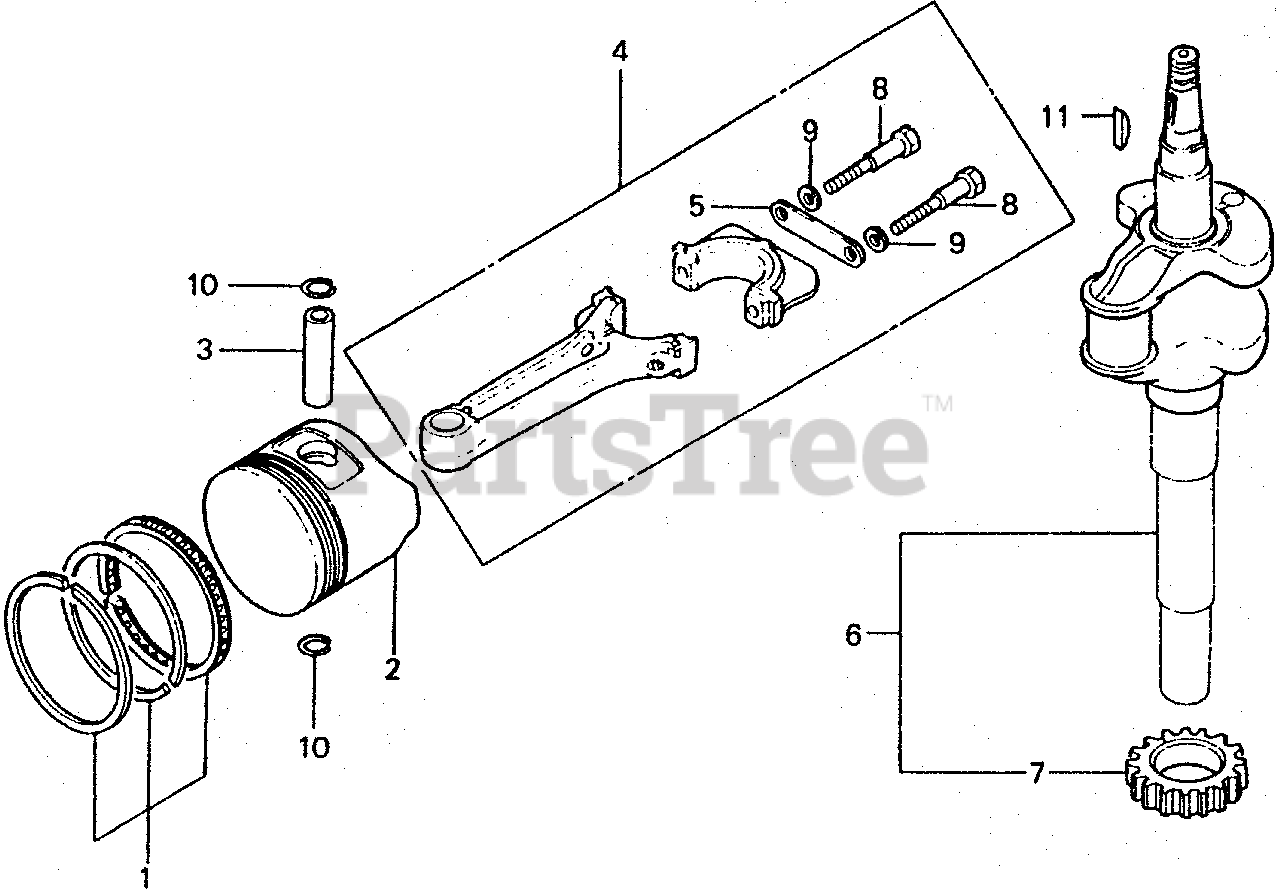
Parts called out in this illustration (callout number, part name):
1	RING SET, PISTON (STD)
1	RING SET, PISTON (0.25) (NOT AVAILABLE)
1	RING SET, PISTON (OS 0.50) (Honda Code 0635060). (OS)
1	RING SET, PISTON (0.75) (OS)
2	PISTON (STD)
2	PISTON (OS 0.25) (OS)
2	PISTON (OS 0.50) (OS)
2	PISTON (0.75) (OS)
3	PIN, PISTON
4	ROD ASSY., CONNECTING
4	ROD ASSY., CONNECTING (Honda Code 0871566). (US 0.25)
5	WASHER, CONNECTING ROD
6	CRANKSHAFT (NOT AVAILABLE)
7	GEAR, TIMING
8	BOLT, CONNECTING ROD (7MM)
9	WASHER, LOCK (7MM)
10	CLIP, PISTON PIN (15MM)
11	KEY, SPECIAL WOODRUFF (25X18)
